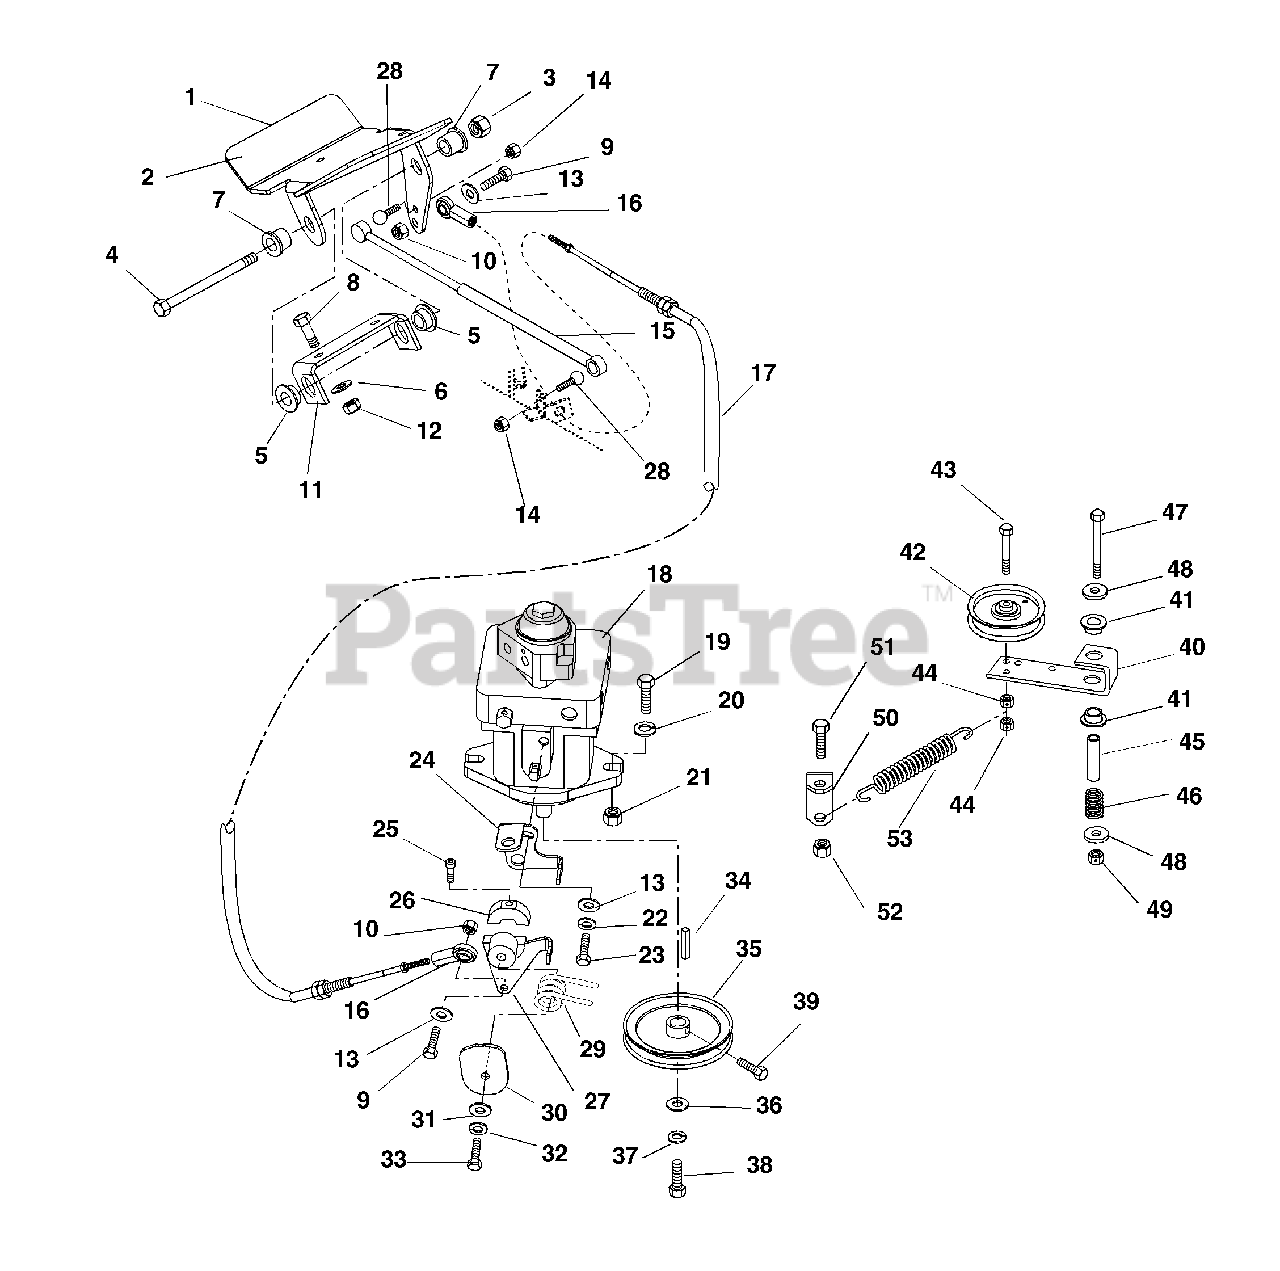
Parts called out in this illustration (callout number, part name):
1	Pedal, Direction Control
2	Pad, Foot Clutch Pedal
3	Nut-Locking-Center .50-13
4	Bolt-Hex .50-13 x 6.50 Grade 5
5	Bushing, Flange-Nylon .762 x 1.00 x .58 x 1.48
6	Washer-Flat-Steel .56 x 1.38 x .109
7	Bushing, Flange-Nylon .515 x .75 x .745 x 1.00
8	Bolt, Hex .38-16 x .75 Grade 5
9	Bolt-Hex .25-20 x 1.00 Grade 5
10	Nut-Locking-Nylon .25-20
11	Bracket, Control Pedal
12	Nut-Locking-Nylon .38-16
13	Washer-Flat-Steel .28 x .62 x .065
14	Nut-Locking-Center .31-18
15	Dampener Control
16	Rod End, Female .25-28
17	Cable, Forward-Reverse Control
18	Pump
19	Bolt-Hex .50-13 x 1.50 Grade 5
20	Washer-Flat-Steel .531 x 1.06 x .095
21	Nut-Locking-Nylon .50-13
22	Washer-Locking-External 262 x .502 x .026
23	Bolt-Hex .25-20 x .75 Grade 5
24	Arm, Neutral Return
25	Screw-Socket Head M6 x 1.00 x 35mm
26	Hub, Pump Neutral
27	Weldment, Pump Neutral
28	Stud, Ball
29	Spring-Torsion .156 x 1.275 x .77
30	Weldment, Pump Neutral
31	Washer-Flat-Steel .344 x .688 x .065
32	Washer-Locking .31 x .078 Regular
33	Bolt-Hex .31-24 x .75 Grade 5
34	Key-Straight 5mm x 25mm x 5mm
35	Sheave, Pump
36	Washer, Flat-Steel .281 x 1.00 x .048
37	Washer-Locking .25 x .062 Regular
38	Bolt-Hex M6 x 1.0 x 12
39	Bolt-Hex .25-20 x .50 Grade 5
40	Arm, Idler Pivot
41	Bushing-Flange Nylon .762 x 1.00 x .58 x 1.48
42	Idler-V 4.00 x .38
43	Bolt-Hex .38-16 x 2.25 Grade 5
44	Nut-Locking-Center .38-16
45	Spacer, Steel .56 x .75 x 2.44
46	Spring-Compression .09 x .80 x 1.00
47	Bolt-Hex .50-13 x 3.50 Grade 5
48	Washer Flat Steel .53 x 1.25 x .100
49	Nut-Locking-Nylon .50-13
50	Anchor, Spring Idler
51	Bolt-Hex .38-16 x 1.00 Grade 5
52	Nut-Locking-Nylon .38-16
53	Spring, Extension
